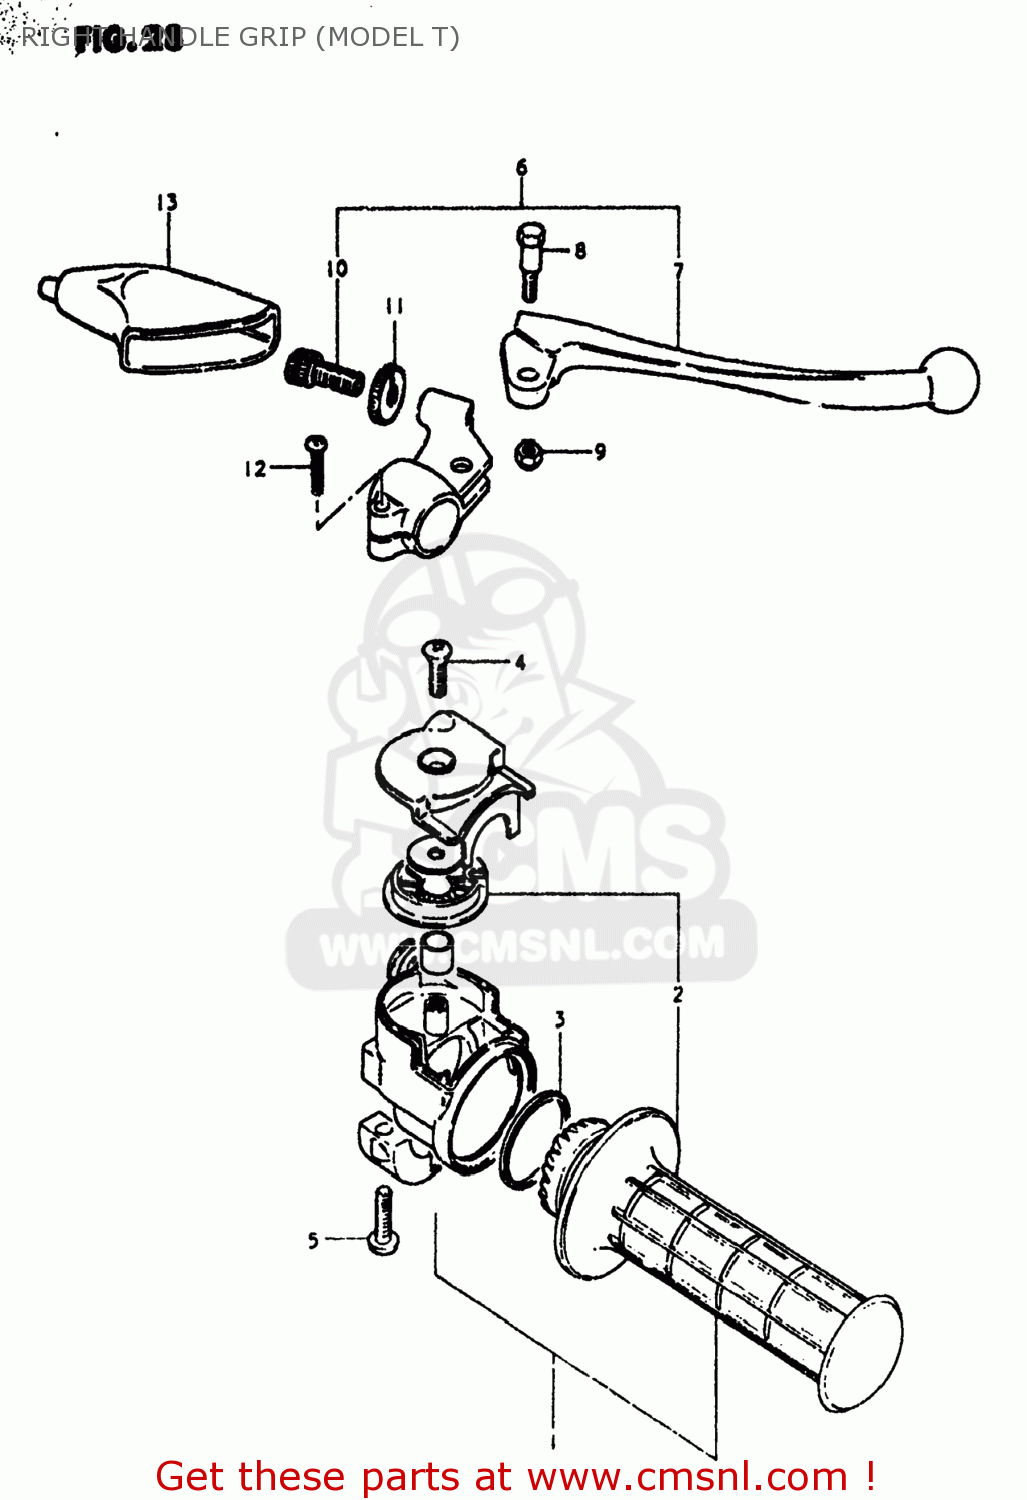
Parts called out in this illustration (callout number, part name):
1	CASE ASSEMBLY,THROTTLE
2	GRIP SET,THROTTLE
3	V-RING,THROTTLE GRIP
4	SCREW
5	SCREW 5X20
6	LEVER ASSY,BRAKE
7	LEVER,BRAKE
8	BOLT,LEVER
9	NUT 6MM
10	ADJUSTER,CABLE
11	NUT,CABLE ADJUSTER
12	SCREW
13	COVER,CLUTCH LEVER
